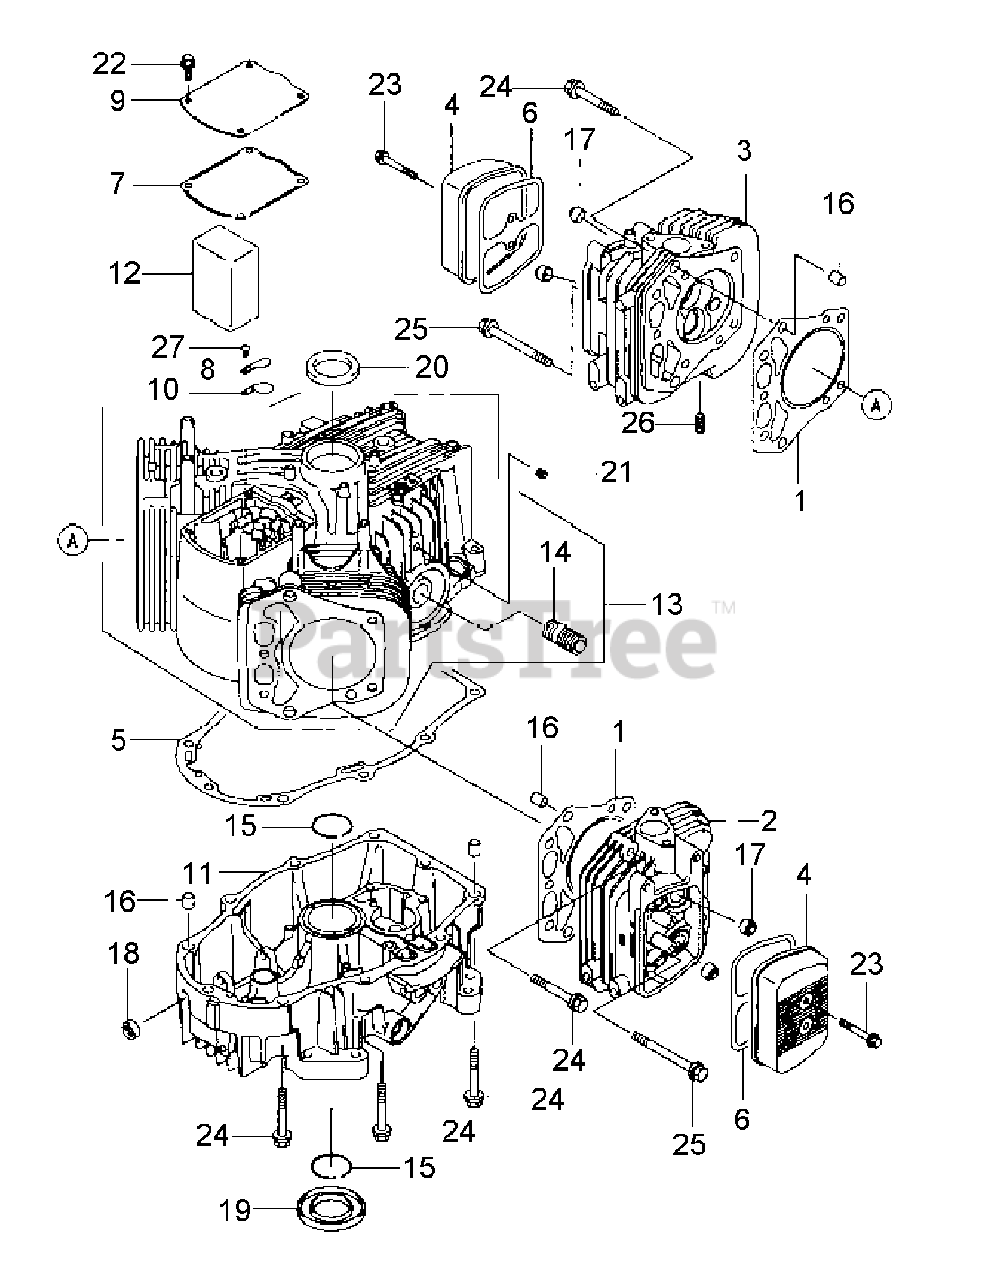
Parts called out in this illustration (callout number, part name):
2	HEAD-COMP-CYLINDER, #2
3	HEAD-COMP-CYLINDER, #1
4	CASE-ROCKER
6	GASKET, ROCKER CASE
7	GASKET, BREATHER
11	COVER-CRANKCASE
12	BREATHER ELEMENT
13	CRANKCASE-COMP
17	SEAL-OIL,RVC2 6X11X10.2
18	SEAL-OIL,SO 8X14X5 HS
19	SEAL-OIL, SD 35X62X8 L HS
20	SEAL-OIL, SD 35X52X7 R HS
22	FLANGED BOLT
23	FLANGED BOLT
24	FLANGED BOLT
25	FLANGED BOLT
